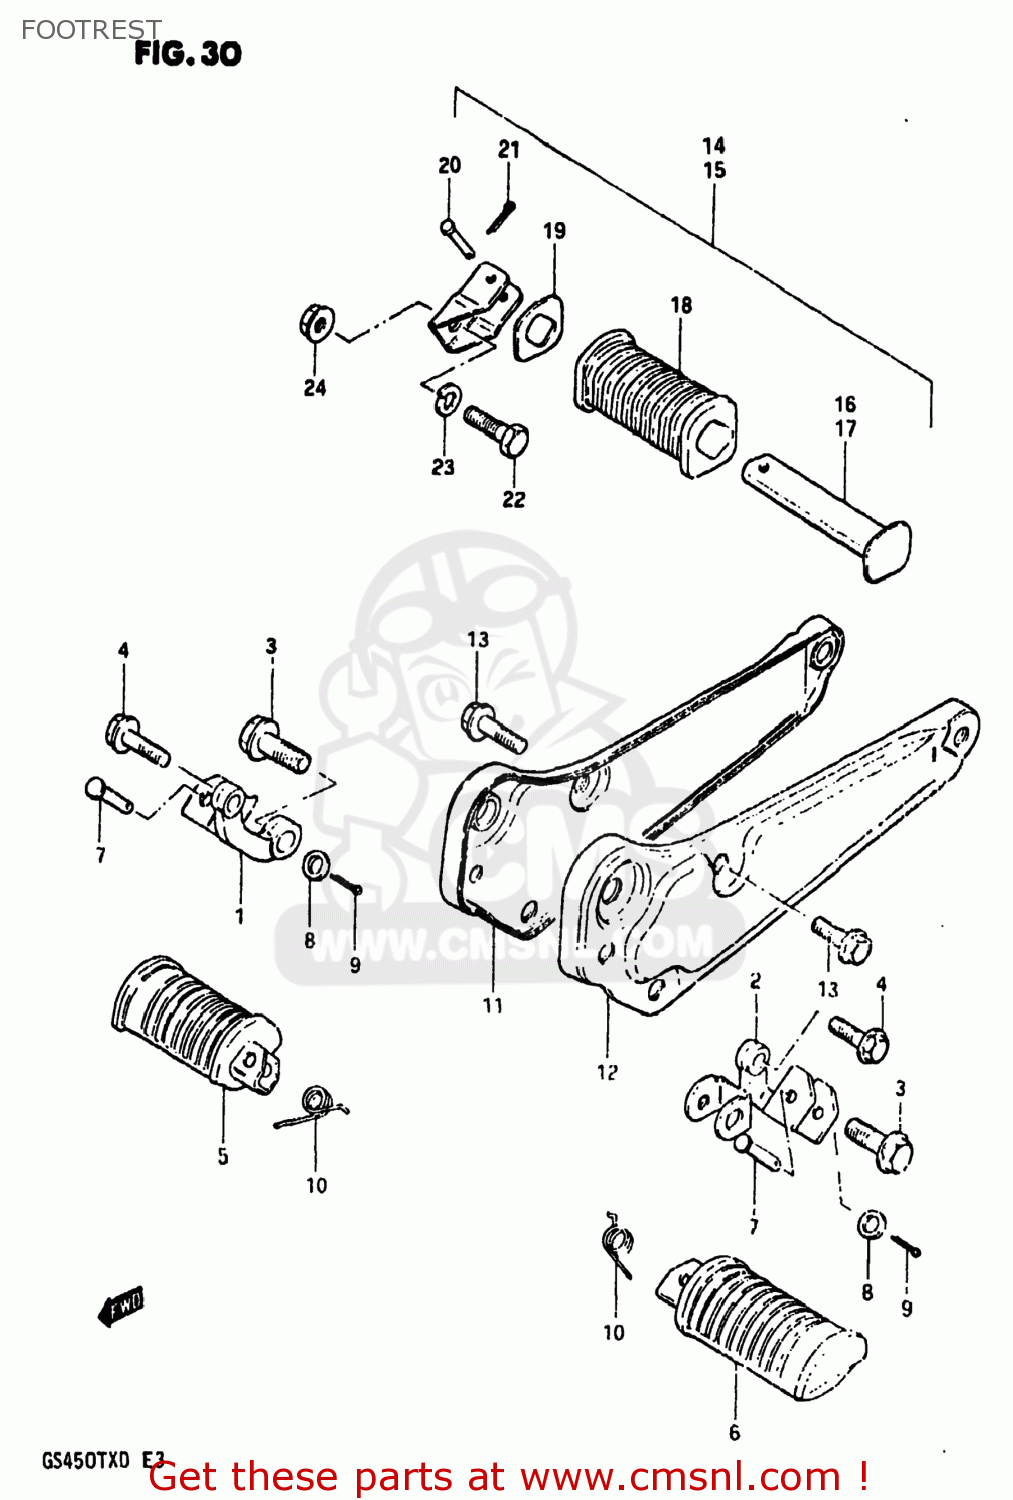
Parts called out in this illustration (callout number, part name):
1	BAR,FRONT FOOTREST,RIGHT
2	BAR,FRONT FOOTREST,LEFT
3	BOLT
4	BOLT
5	RUBBER,FRONT FOOTREST
6	FOOTREST
7	PIN
8	WASHER
9	PIN 20X20
10	SPRING
11	BRACKET,MUFFLER,RIGHT
12	BRACKET,MUFFLER,LEFT
13	BOLT
14	FOOTREST ASSY,PILLION,R
15	FOOTREST ASSY,PILLION,L
16	BAR,REAR FOOTREST,RIGHT
17	BAR,REAR FOOTREST,LEFT
18	RUBBER,PILLION FOOTREST
19	WASHER,FOOTREST RUBBER
20	PIN
21	PIN 20X20
22	BOLT,M10X1.25X
23	LOCK WASHER
24	NUT
